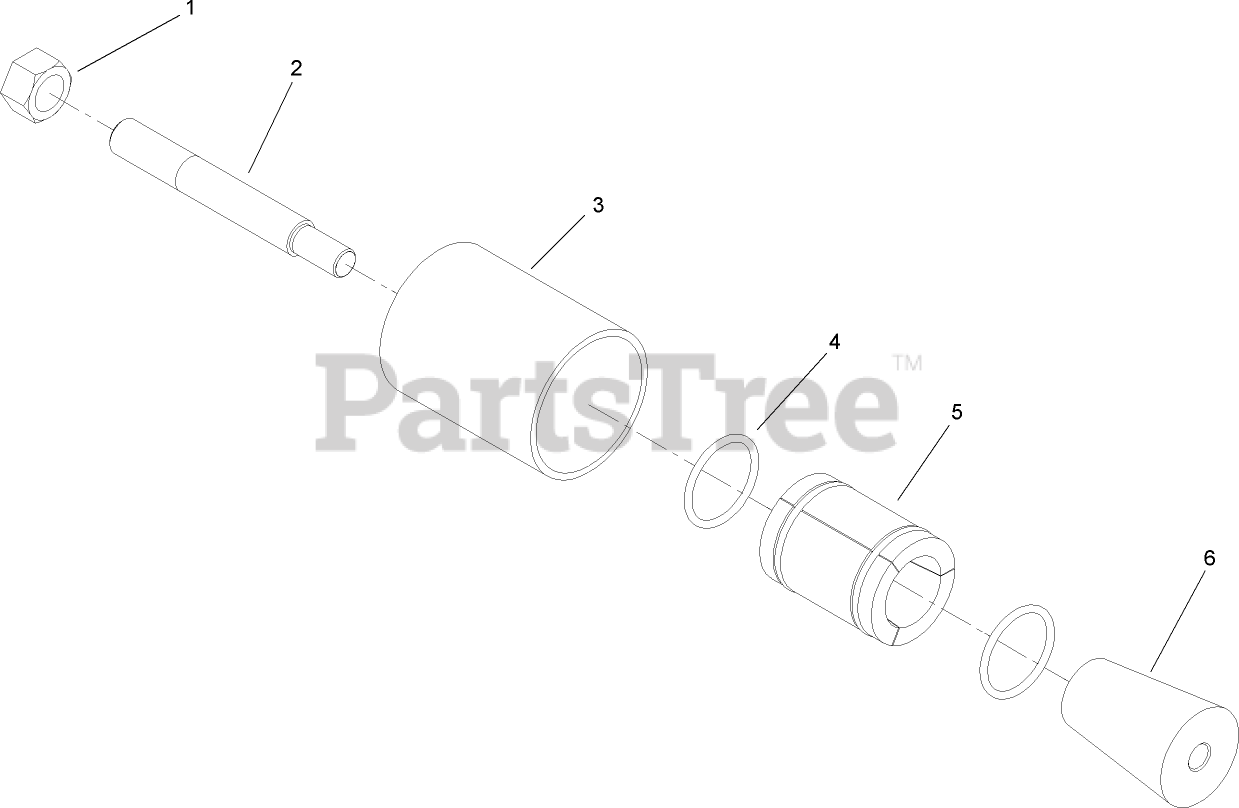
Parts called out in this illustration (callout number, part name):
1	NUT-HEX
2	ROD-PULLER
3	GRIP-OUTER
4	O-RING
5	GRIP-INNER
6	CONE-PULLER
